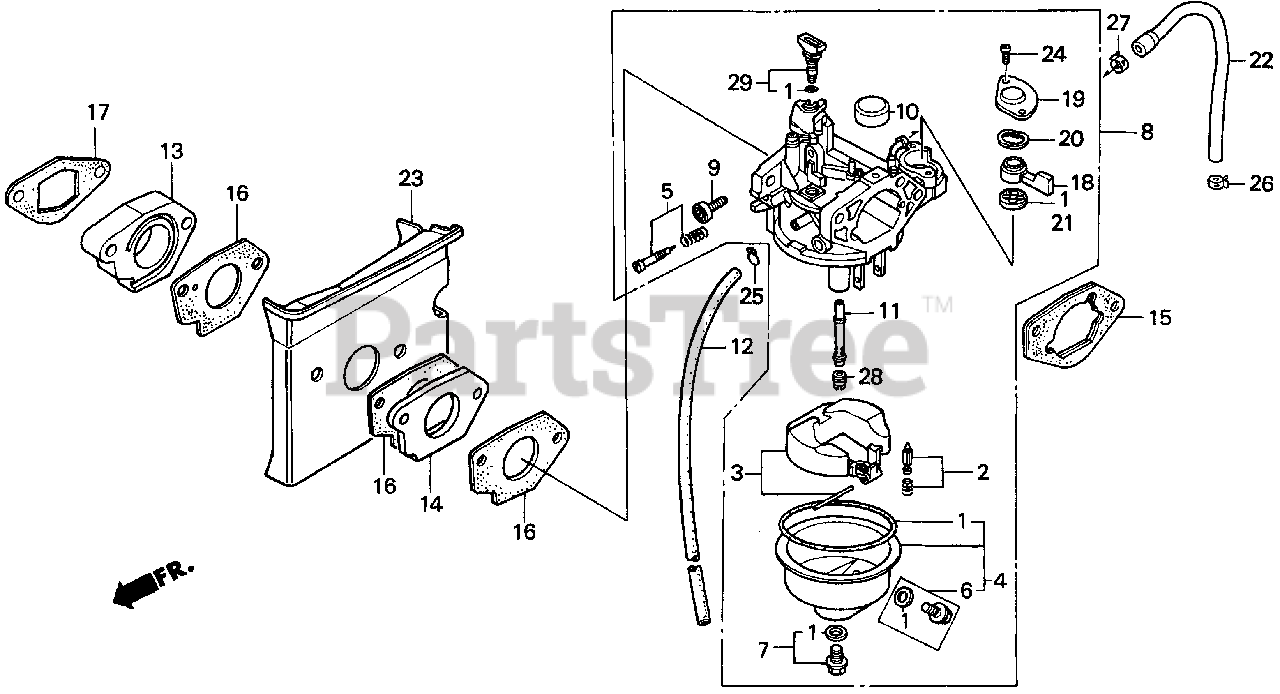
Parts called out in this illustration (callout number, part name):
1	GASKET SET
1	GASKET SET (EXC. 16173-001-004) (CARBURETOR NO.) (EXCEPT 16173-001-004)
2	VALVE SET, FLOAT
3	FLOAT SET
4	CHAMBER SET, FLOAT
5	SCREW SET, PILOT (Honda Code 1441500). (CARBURETOR NO.)
6	SCREW SET, DRAIN (Honda Code 1672187). (CARBURETOR NO.)
7	SCREW SET
8	CARBURETOR ASSY. (BB36A B)
8	CARBURETOR ASSY. (BB36A C)
9	SCREW, THROTTLE STOP
10	CAP, CHOKE LEVER DUST
11	NOZZLE, MAIN
12	TUBE, AIR VENT
13	INSULATOR, CARBURETOR
14	INSULATOR, CARBURETOR
15	SPACER, CARBURETOR
16	GASKET, CARBURETOR
17	GASKET, INSULATOR
18	LEVER, VALVE
19	PLATE, LEVER SETTING (CARBURETOR NO.)
20	SPRING, PETCOCK LEVER (CARBURETOR NO.)
21	GASKET, VALVE
23	GUIDE, AIR
24	SCREW, PAN (3X6)
24	SCREW, PAN (3X8)
25	CLIP, TUBE (B8)
28	JET, MAIN (#82)
28	JET, MAIN (#85) Use up to Engine SN BE81B B.
28	JET, MAIN (#88) Use up to Engine SN BE81B B.
29	JET SET, PILOT (#40)
